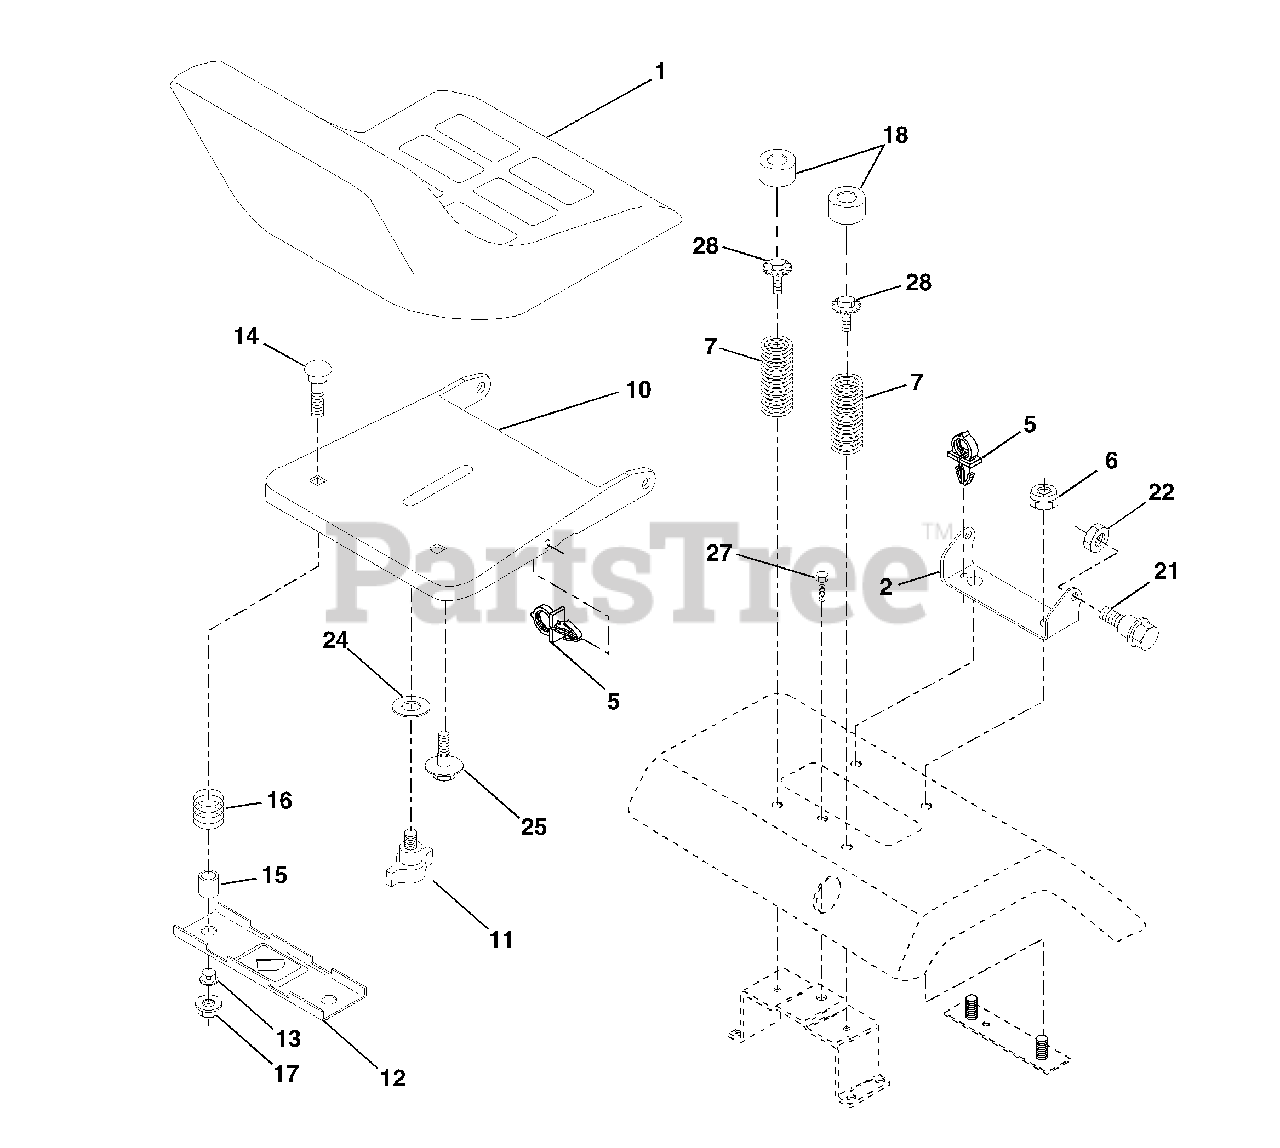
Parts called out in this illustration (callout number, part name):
1	Seat
2	Pivot Bracket, Seat
5	Clip, Push-in Hinged
6	Nut, Lock Hex w/Ins 3/8-16 UNC
7	Spring, Seat
10	Pan, Seat
11	Knob, Seat, Black
12	Bracket, Switch Mounting
13	Bushing, Snap, Black, Nylon
14	Bolt, Carriage 1/4-20 x 1-1/2
15	Spacer, Split .28 x .96
16	Spring
17	Locknut, Flange 1/4 Grade 5
18	Cap Spring Seat Blk 1.75 x 1.0
21	Bolt, Shoulder 5/16-18 Unc -2A
22	Nut Lock Hex W/Ins 5/16-18 Unc
24	Washer 17/32 x 1-3/16 x 12 Gauge
25	Bolt, Shoulder 5/16-18 x .62
27	Screw Thdrol 3/8-16 x 3/4
28	Bolt 5/16-18 UNC x 3/4 w/Sems
